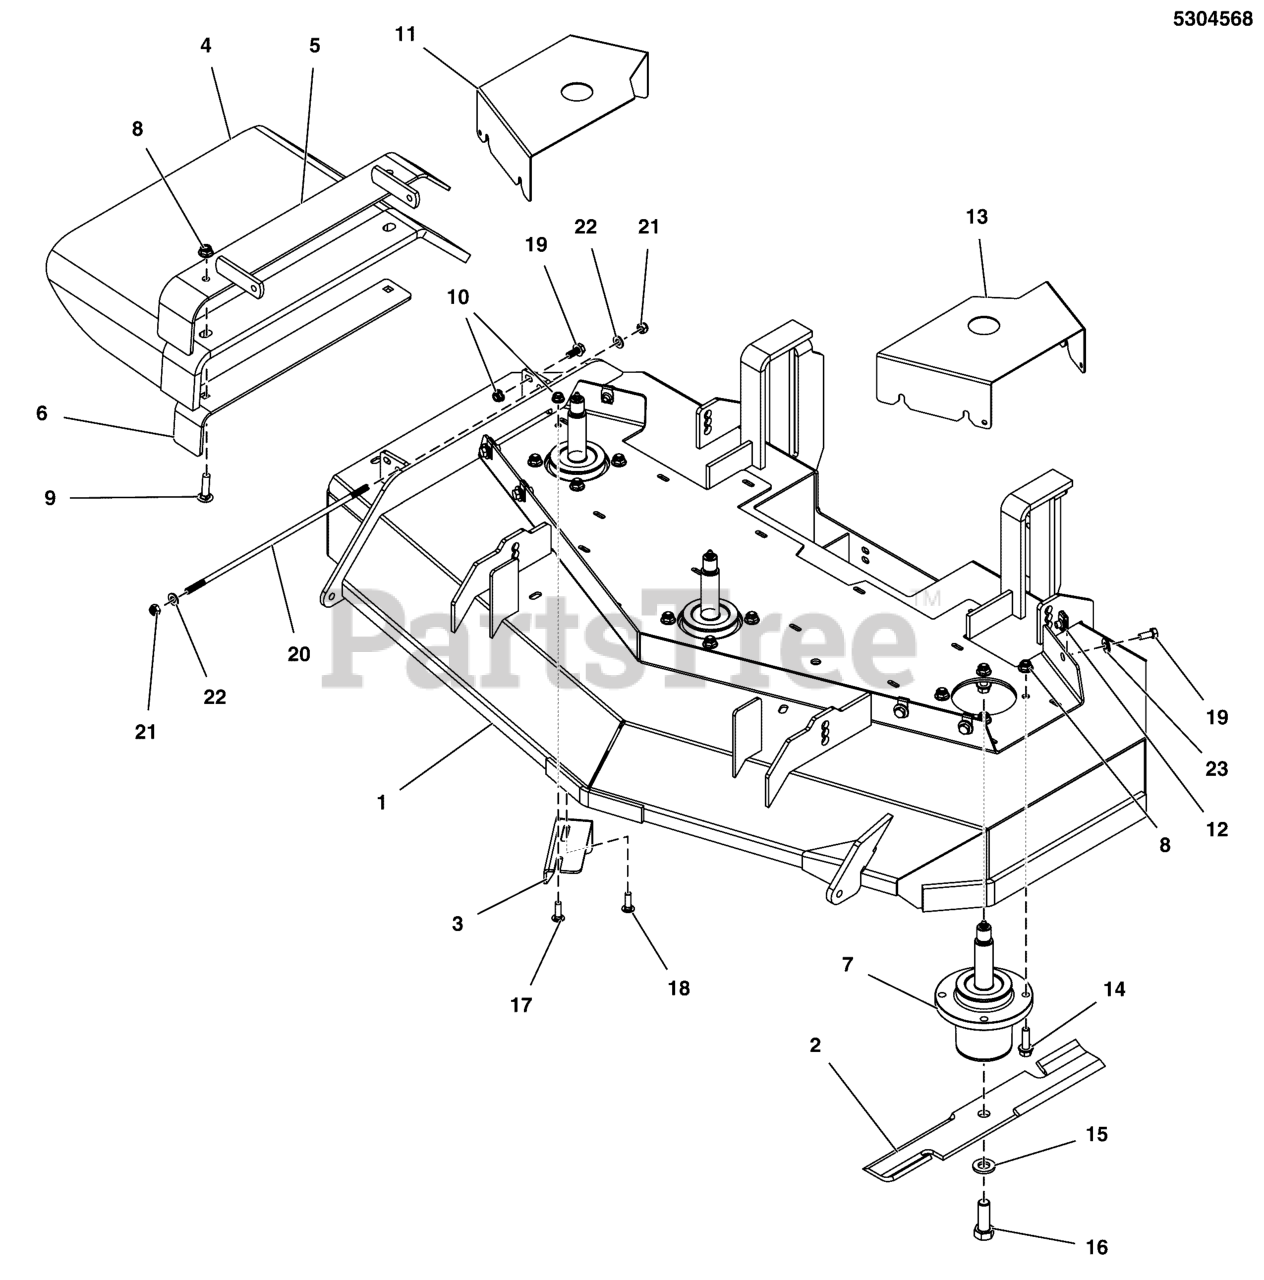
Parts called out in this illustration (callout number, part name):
1	DECK SHELL W/DECALS, 48, SRSZ1 (5415014B)
2	BLADES, SET OF THREE (3); 16.25 X.25 X 2.5, 1 X 3.5
3	PLATE, DEFLECTOR - BLK
4	CHUTE, RUBBER DISCHARGE CHUTE (5104441)
5	WELD, MOUNT, DISCHARGE CHUTE - BLK
6	SUPPORT, DISCHARGE CHUTE - BLK
7	SPINDLE ASSM, ALUMINUM, LONG SHAFT
8	NUT, 3/8 - 16 HEX NYLOCK FLANGE
9	BOLT, 3/8-16 X 1-1/2, CARRIAGE, GD5, CZ
10	NUT, 5/16-18 HEX NYLOCK FLANGE NUT
11	GUARD, MOWER DECK, RH - RED
12	BODY CLIP, 5/16-18-7GA MATERIAL
13	GUARD, MOWER DECK, LH - RED
14	BOLT, 3/8-16 X 1-1/4, FLANGE, GD 5, CZ
15	WASHER, BLADE BOLT, 9/16" F436, CZ
16	BOLT, 5/8-11 X 1-3/4 GD8
17	BOLT, 5/16-18 X 1, CARRIAGE, GD5, CZ
18	BOLT, 5/16-18 X 3/4, CARRIAGE, GD5, CZ
19	BOLT, 5/16-18 X 3/4 GD5
20	ROD, 5/16 X 13.75, TBE, CZ
21	NUT, 5/16-24 HEX NYLON LOCK
22	WASHER, 5/16" SAE
23	WASHER, 5/16 GRADE 9, FLAT
